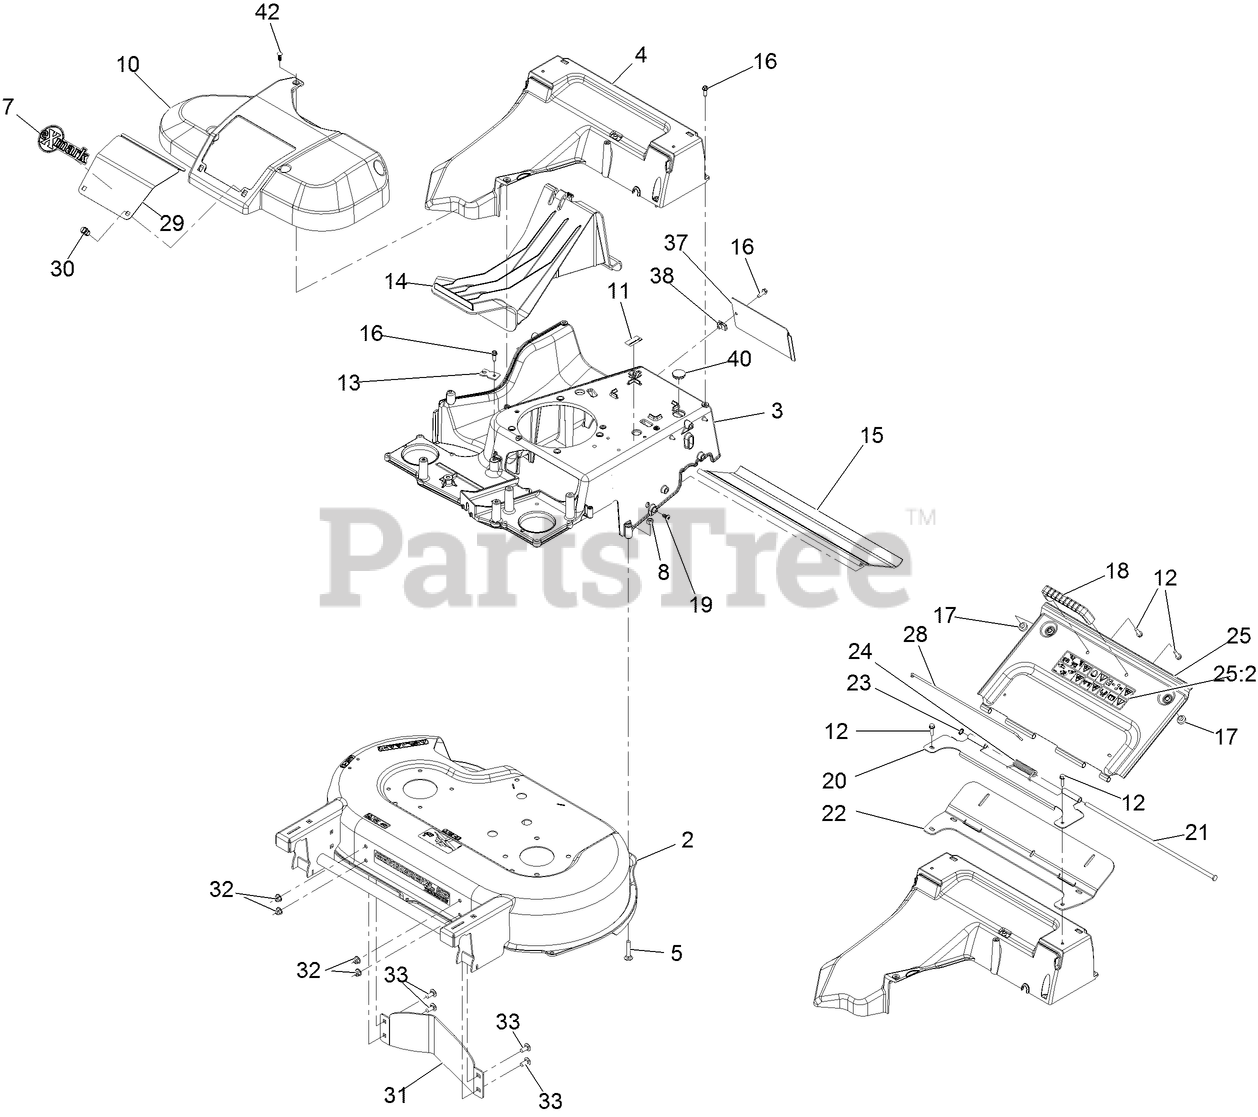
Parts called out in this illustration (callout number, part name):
2	DECK-30, X-SERIES W/DECALS
3	FRAME
5	BOLT-CAR
7	DECAL-EXMARK LOGO
8	NUT-LOCK, NI
10	COVER-BELT
11	Decal-Patent Ttco.Com
12	SCREW-HWH
13	BRACKET-CABLE, TRACTION
14	PLUG-MULCH
15	SHIELD-TRAILING
16	SCREW-HWHTF
18	HANDLE-DOOR
19	SCREW-PTH
20	BRACKET-HINGE
21	PIN-HINGE
22	SEAL-DOOR
23	RING-RETAINING
24	SPRING-TORSION, COVER
25	REAR DOOR ASM
25:2	DECAL-WARNING
28	CLIP-SEAL
29	DOOR-ACCESS
30	FASTENER
31	BAFFLE-CONTROL
32	NUT-HF, NI
33	SCREW-HSBH
37	Cover-Frame
40	PLUG-BUTTON
42	Clip-Xmas Tree
